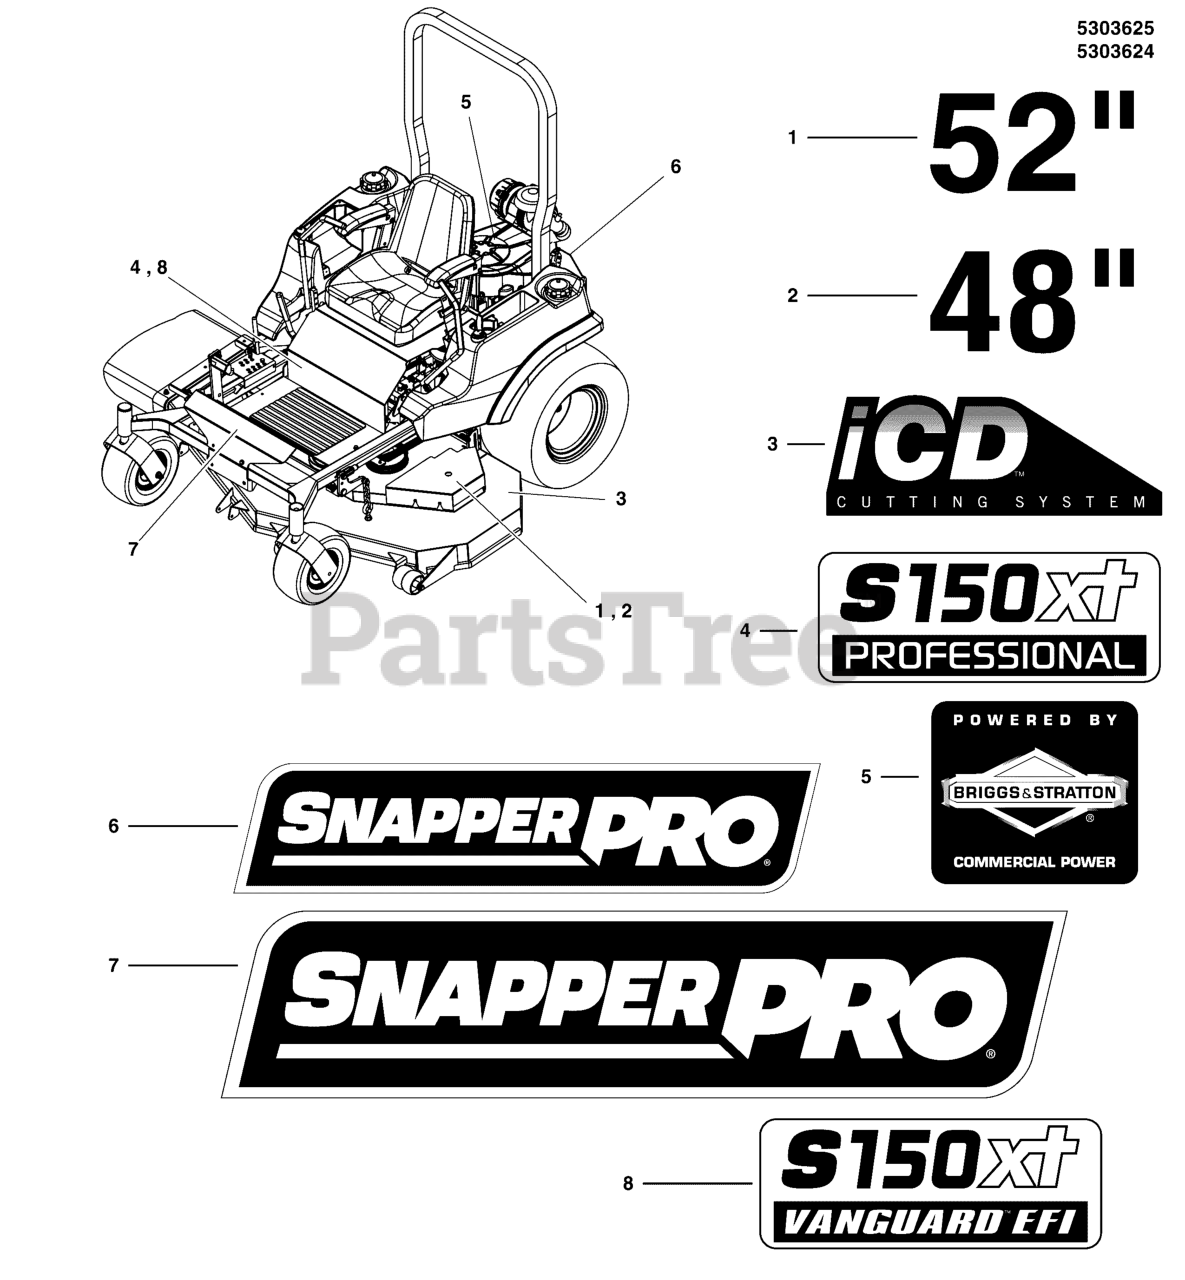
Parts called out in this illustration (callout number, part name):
1	DECAL, 52
2	DECAL, 48
3	DECAL, iCD CUTTING SYSTEM
4	DECAL, S150XT (2014)
6	DECAL, SNAPPER PRO LOGO, SMALL
7	DECAL, SNAPPER PRO LOGO, MEDIUM
8	DECAL, MODEL SERIES, S150XT, EFI
